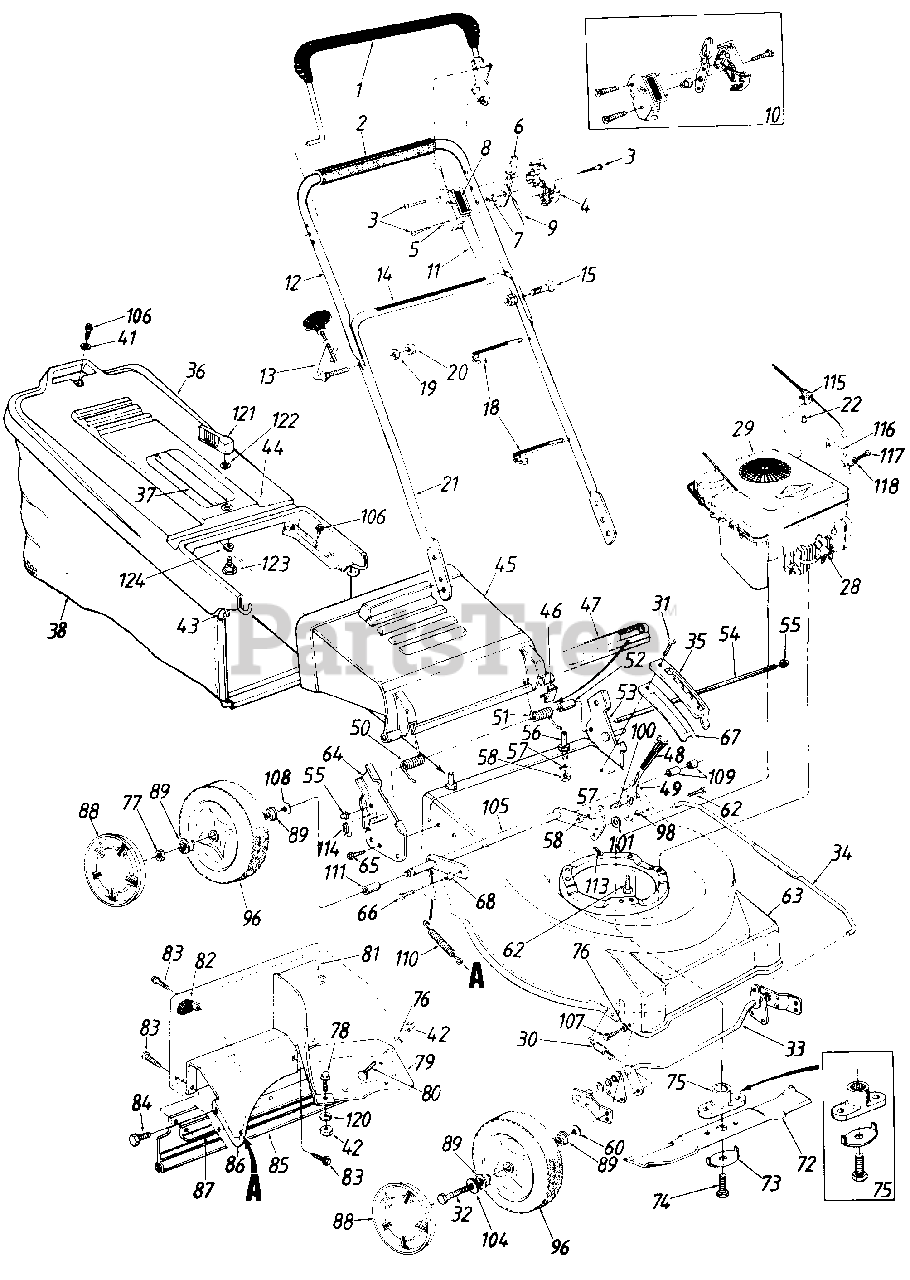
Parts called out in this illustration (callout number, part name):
1	Control Handle Ass'y.
2	Foam Grip
3	Truss Mach. B-Tap Scr. #12 x 1.5" Lg.
4	Control Panel Half
5	Clutch Panel Half
6	Throttle Control Lever
7	Control Disc Pin
8	Control Label-Throttle
9	Throttle Wire-53" Lg.
10	Control Housing Comp.
11	Control Cable-46" Lg.
12	Upper Handle
13	Rope Guide Bolt
14	Instruction Label-Handle
15	Curved Carriage Bolt 5/16-18 x 1.38" Lg.
18	Cable Tie
19	L-Wash. 5/16" I.D.
20	Hex Nut 5/16-18 Thd.
21	Lower Handle
22	Pop Rivet .156" Dia. x .379"
28	Spark Plug Boot
29	Engine
30	Extension Spring 2.39" Lg.
31	Torx Hd. AB-Tap Scr. 1/4"-.62" Lg.
34	Height Adj. Connecting Rod
35	Height Adjustment Plate
36	Hardtop Bag Cover
37	Hardtop Handle
38	Grass Bag
41	Fl-Wash. .281" I.D. x .62" O.D.
42	Hex Nut 1/4-20 Thd.
43	Front Catcher Frame
44	Rear Catcher Frame
45	Chute Deflector
46	Deflector Plug
47	Seal-Extrusion
49	Spring Lever
50	Torsion Spring-R.H.
51	Torsion Spring-L.H.
52	Spacer.255" l.D.
53	Handle Brkt. Ass'y.-L.H.
54	Hinge Pin 17.75" Lg.
55	Cap Speed Nut
56	Shld. Pin 3/8-24 x 1.43" Lg.
57	L-Wash. 3/8" I.D.
58	Hex Jam Nut 3/8-24 Thd.
60	Bell-Wash. .38" I.D. x .88" O.D.
62	Hex L-Wash. Hd. Scr. 3/8-16 x 1 " Lg.
63	21" Deck Ass'y.
64	Handle Brkt. Ass'y.-R.H.
65	Hex L-Wash. Hd. AB-Tap Scr. 1/4 x.62" Lg.
66	Hex Wash. Hd. Tap Scr. 3/8-16 x .75" Lg.
67	Height Adjustment Support
68	Spacer.385" I.D.
72	21" Blade
73	Blade Bell-Wash. .44" I.D. x 2.38"
74	Hex Bolt 7/16-20 x 1.5" Lg.
75	Blade Adapter Kit
76	L-Wash. 1/4" I.D.
77	Hex Jam Nut 1/2-20 Thd.
78	Hex Bolt 1/4-20 X .85" Lg.
79	Rear Belt Baffle
80	Carr. Bolt 1/4-20 X .50" Lg.
83	Torx Mach. AB-Tap Scr. 1/4 X .62" Lg.
84	Hex B-Tap Scr. 1/4 X .38" Lg.
89	Ball Bearing
96	Wheel Ass'y. Comp.
98	Shld. Spacer .50" Dia.
100	Shld. Pin 3/8-24 x 1.43" Lg.
101	Fl-Wash. .375" I.D. x 1.0"
104	Fl-Wash. .531" I.D. x .93"
105	Rear Axle Ass'y.
106	Hex L-Wash. AB-Tap Scr. 1/4 x .62" Lg.
107	Hex L-Wash. HD AB-Tap Scr. 1/4 x .38" Lg.
108	Fl-Wash. .510" I.D. x .75"
109	Spacer.526" I.D.
110	Extension Spring 3.8" Lg.
111	Sleeve.526" I.D.
113	Cotter Pin 3132" Dia. x .75"
114	Internal Cotter Pin 5/16n Dia.
115	Cable Mtg. Brkt.
116	Mounting Brkt.
117	Truss Mach. Scr. #10 x .5ll Lg.
118	L-Wash. #10 I.D.
120	Bell-Wash. 1/4" I.D.
121	Grass Catcher Locking Knob
122	Internal L-Wash. 1/4" I.D.
123	Shld. Bolt .342"
124	Wave Washer 3/8" I.D.
